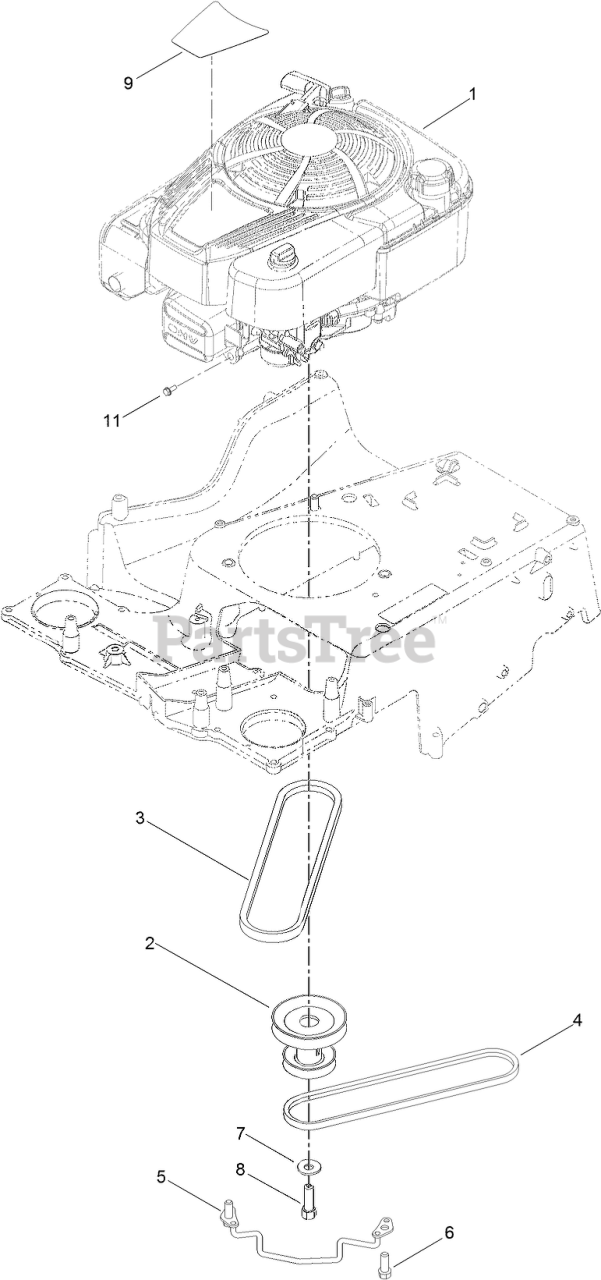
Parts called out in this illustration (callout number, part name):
2	PULLEY-ENGINE
3	V-BELT
4	V-BELT, TRACTION
5	GUIDE-BELT
6	SCREW-TAPTITE
7	WASHER-BELLEVILLE
8	SCREW-HH
9	DECAL-SHROUD
11	SCREW-TAPTITE
